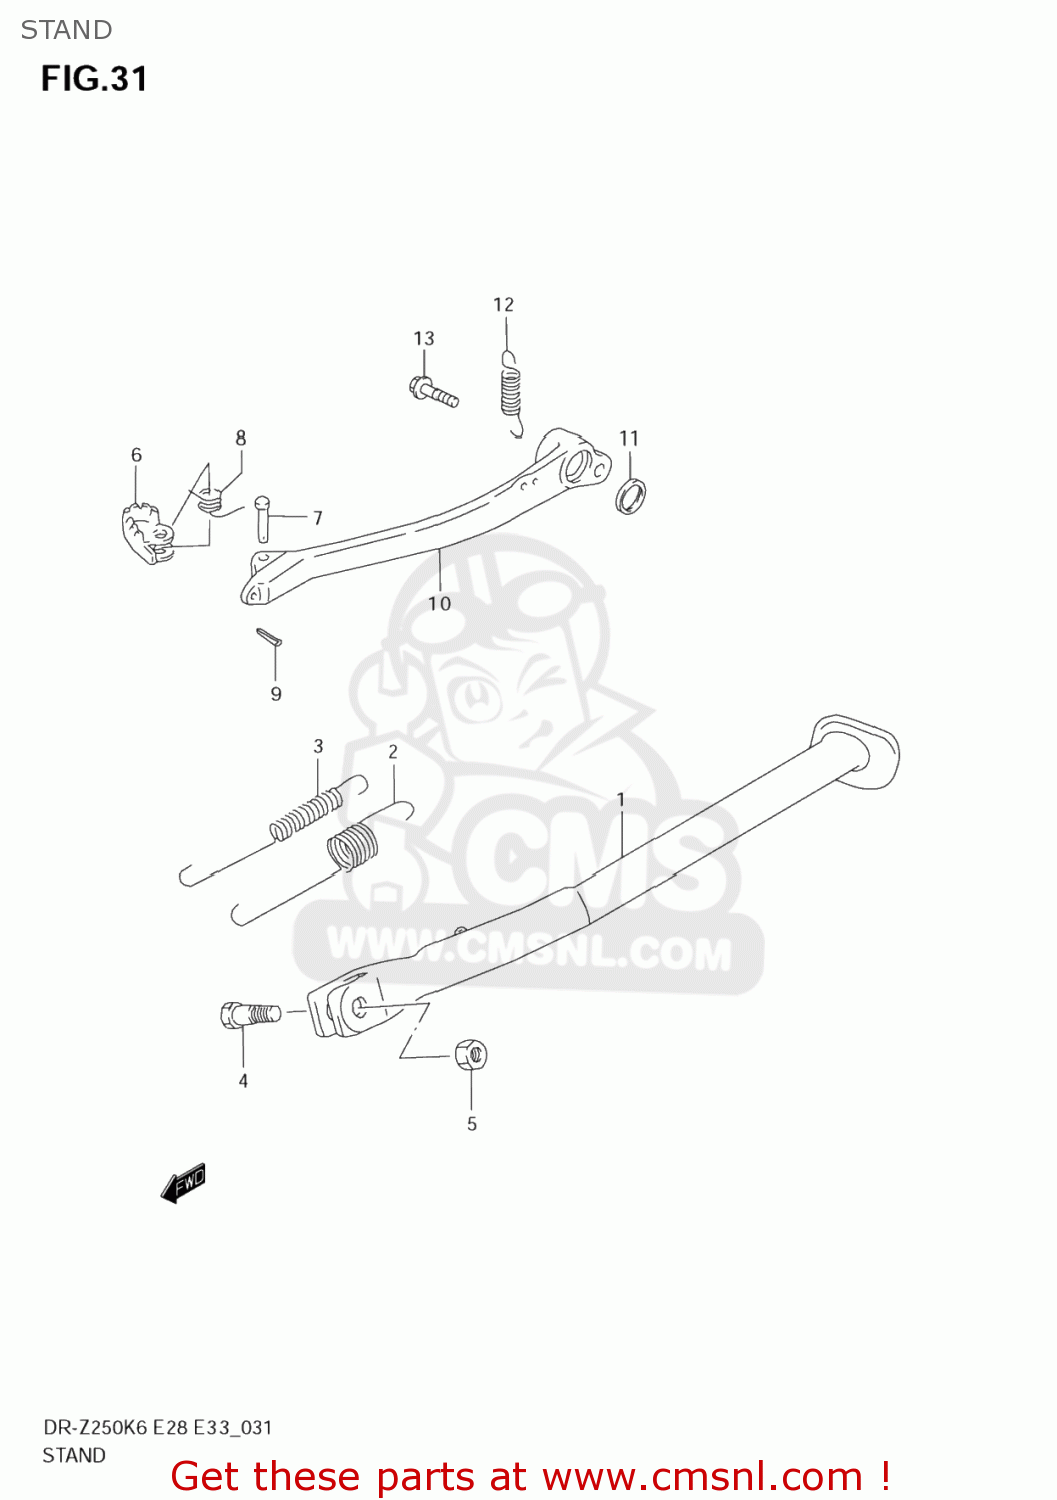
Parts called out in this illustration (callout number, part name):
1	STAND,PROP
2	SPRING
3	SPRING
4	BOLT(10X30)
5	NUT
6	PEDAL,BRAKE
7	PIN(6X23.5)
8	SPRING
9	PIN
10	ARM,BRAKE PEDAL
11	SEAL,OIL(15X21X3)
12	SPRING
13	BOLT(8X14)
